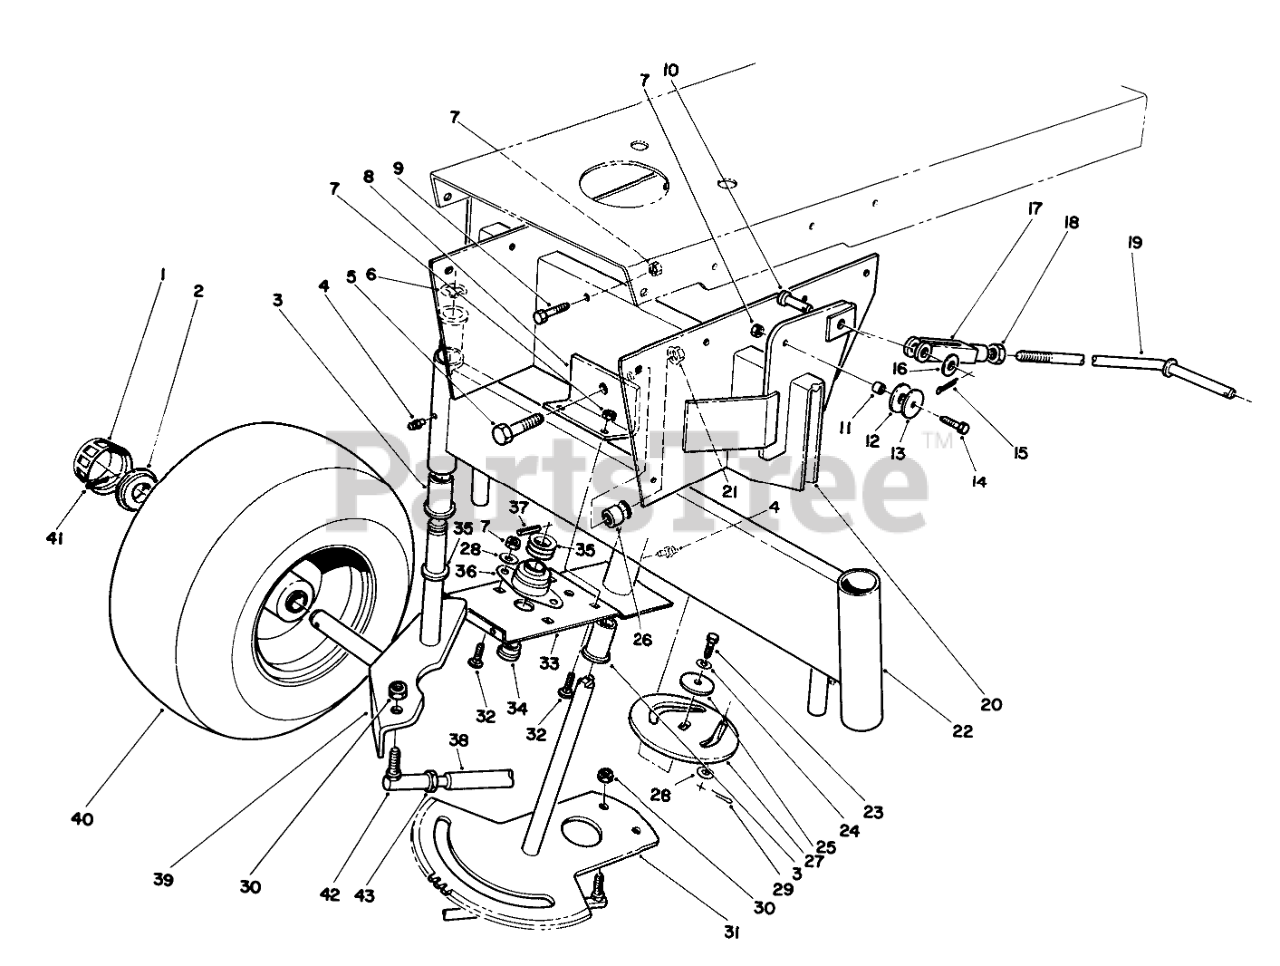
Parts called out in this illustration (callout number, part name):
1	CAP-HUB
2	FRONT WHEEL SPACER
3	BUSHING PM
4	GREASE FITTING
5	Capscrew
6	E-RING
7	NUT-LOCK, NI
8	SPINDLE SPROCKET BRKTB
9	SCREW-HH
10	PIN-CLEVIS
11	FLOOR SPACER
12	WASHER-RUBBER
13	WASHER-FLAT
14	SCREW-HH
15	PIN-COTTER
16	WASHER-FLAT
18	NUT-JAM
19	FRONT LINK
20	Support-Front Axle
21	NUT-HF
22	Axle-Front (Incl. Ref. #3 & 4)
23	SCREW-HH
24	WASHER-LOCK
25	SPACER
26	SPACER-AXLE, FRONT
27	PLATE-PULL ROD
28	WASHER-PLAIN
29	PIN-COTTER
30	NUT-LOCK
31	STEERING RACK WA B
32	SCREW-CARR
33	Spindle-Steering Rack (Incl. Ref. #3 & 4)
34	BEARING-FLANGE
35	WASHER-THRUST
36	BUSHING
37	PIN-ROLL, SLOTTED
38	TIE ROD
39	R/H SPINDLE WA
40	Tire & Wheel Assy-Front
41	PIN-COTTER
42	JOINT-BALL, RH THREADED
43	NUT-HJ
